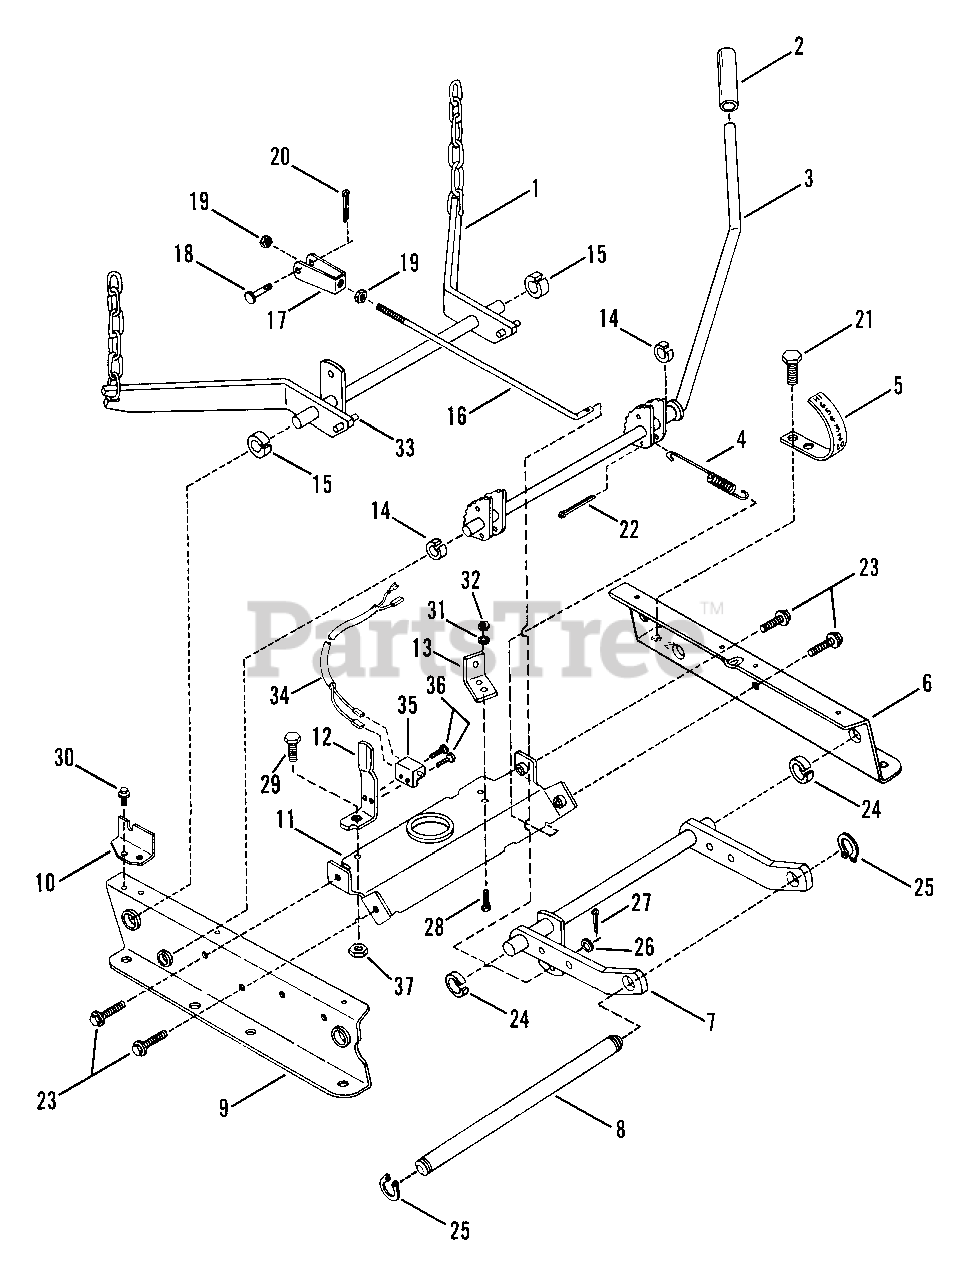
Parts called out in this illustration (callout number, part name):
1	ASSEMBLY, REAR LIFT ARM
2	GRIP, Cam Lift Lever
3	CAM LIFT LEVER
4	SPRING, Cam Lift
5	PLATE, Indicator
6	RAIL, Left Hand
7	ASSEMBLY, FRONT LIFT ARM
8	SUPPORT ROD (Front Lift Arm to Frame Front End)
9	RAIL, Right Hand
10	BRACKET, Cable
11	BRACE, Top Rail
12	GUIDE, Belt
13	ANCHOR
14	RING, White
15	RING, Blue
16	ROD, Timing
17	CLEVIS, Timing Rod
18	PIN, 3/8 x 1 1/16" Clevis
19	NUT, 3/8-24 Hex
20	COTTER-PIN, 3/32 x 3/4"
21	SCREW, 3/8-24 x 3/4" Hex Head Cap
22	COTTER-PIN, 5/32 x 1"
23	SCREW, 3/8-16 x 1" Hex Head Self-Tapping
24	RING, Red
25	RING, 5/8" External Retaining
26	WASHER, 3/8" Flat
27	COTTER-PIN, 1/8 x 3/4"
28	SCREW, 5/16-24 x 3/4" Hex Head Cap
29	BOLT, 5/16-18 x 3/4" Hex Flange Lock
30	SCREW, 1/4-20 x 1/2" Hex Head Cap Self-Tapping
31	WASHER, 5/16 Internal Tooth Lock
32	NUT, 5/16-24 Hex
33	PIN, Roll
34	WIRE, Mower Deck
35	SWITCH, Interlock
36	SCREW, #10-24 x 1/2" Hex Washer Self-Tap (Torx)
37	NUT, 5/16-18 Hex Flange Lock
